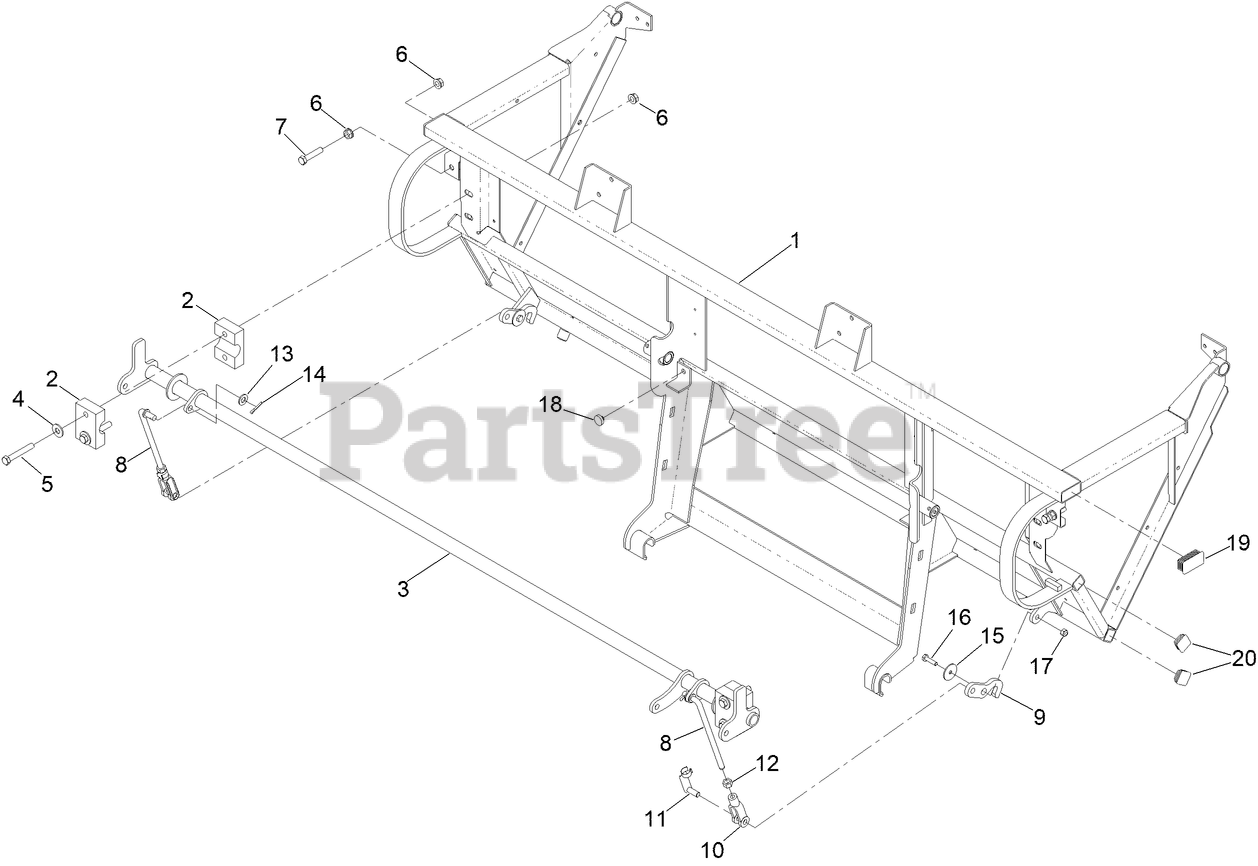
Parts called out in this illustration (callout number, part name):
3	LINK-INTERMEDIATE
4	WASHER-FLAT
5	SCREW-HH
6	NUT-HHF, WHIZ
7	SCREW-HH
8	LINK-HANDLE
10	YOKE-LINKAGE, BRAKE
11	PIN-SPRING, CLEVIS
12	NUT-HEX
13	WASHER-FLAT
14	PIN-COTTER
15	WASHER-FLAT
16	SCREW-HH
17	NUT-LOCK, NI
18	BUMPER
